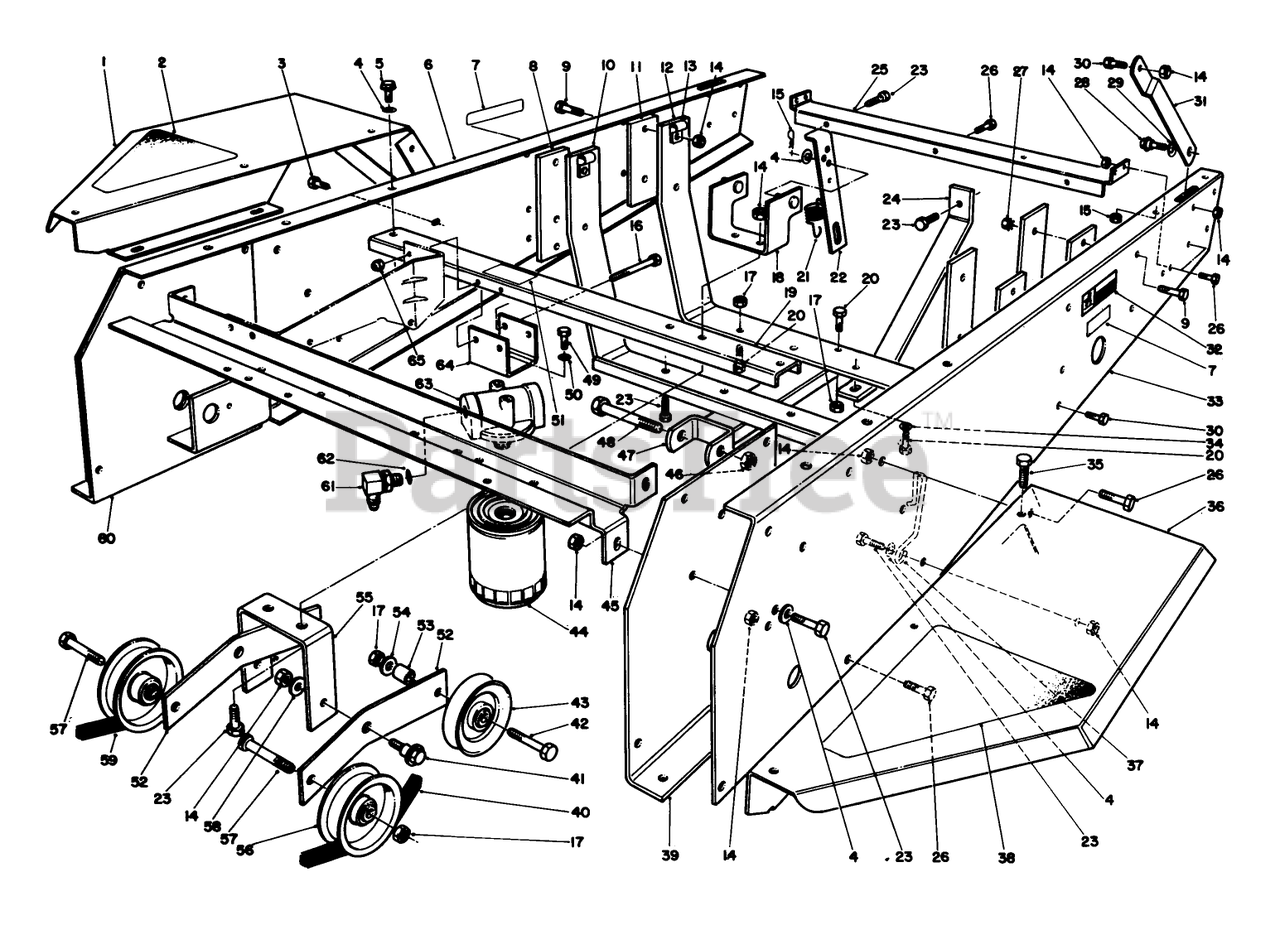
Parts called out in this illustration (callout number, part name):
3	SCREW-HHF
4	WASHER-PLAIN
5	SCREW-THD ROLL, HWH
7	DECAL-ROTATING
8	FRONT ENG PLATE
9	SCREW-HH
10	ENGINE MT WA *B
11	REAR ENG PLATE
14	NUT-LOCK, NI
15	PIN-COTTER
16	SCREW-HH
17	NUT-LOCK, NI
19	MIDDLE CHANNEL WA *B
20	SCREW-HH
21	IDLER SPRING
23	SCREW-HH
26	SCREW-HH
27	NUT-KEPS
28	SCREW-SHOULDER
29	WASHER-SPRING
30	SCREW-HH
32	DECAL-HOT
34	WASHER-LOCK
35	SCREW-HHFTF
37	BELT GUIDE
40	V-BELT, JACKSHAFT
41	SCREW-SHOULDER
42	SCREW-HH
43	PULLEY
44	FILTER-OIL, TRANSMISSION
46	NUT-LOCK
48	SCREW-HH
49	SCREW-HH
50	WASHER-LOCK
51	DECAL-OIL
53	SPACER-WEIGHT
54	WASHER-FLAT
56	PULLEY
57	SCREW-HH
58	WASHER
59	V-BELT, TRACTION
62	O-RING
63	FILTER HD ASM
64	BRACKET - FILTER HEAD
65	NUT-LOCK, NI
